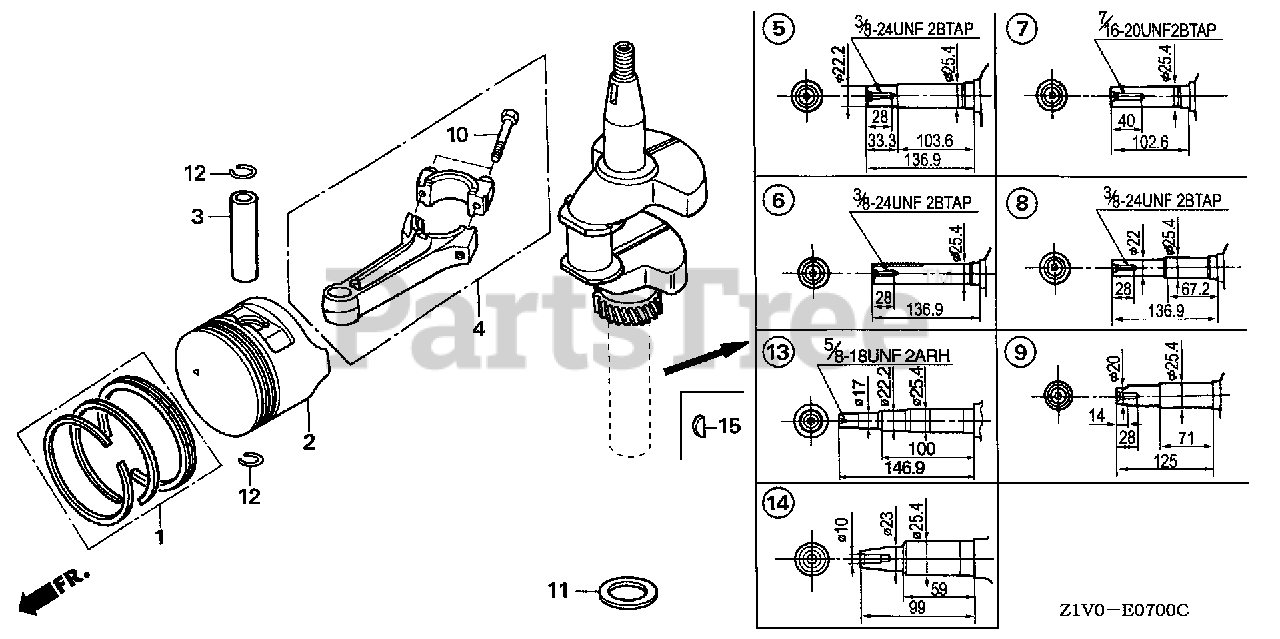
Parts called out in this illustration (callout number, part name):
1	RING SET, PISTON (STD) (TEIKOKU)
1	RING SET, PISTON (STD.) (NIPPON)
1	RING SET, PISTON (0.25) (TEIKOKU)
1	RING SET, PISTON (0.25) (NIPPON)
1	RING SET, PISTON (0.50) (TEIKOKU)
1	RING SET, PISTON (0.50) (NIPPON)
1	RING SET, PISTON (0.75) (TEIKOKU)
1	RING SET, PISTON (0.75) (NIPPON)
2	PISTON (STD)
2	PISTON (0.25)
2	PISTON (0.50)
2	PISTON (0.75)
3	PIN, PISTON
4	ROD ASSY., CONNECTING
10	BOLT, CONNECTING ROD
11	WASHER, THRUST (25.6MM)
12	CLIP, PISTON PIN (18MM)
13	CRANKSHAFT (FOR TORO 22196/22296 SEE PIB 15-02)
